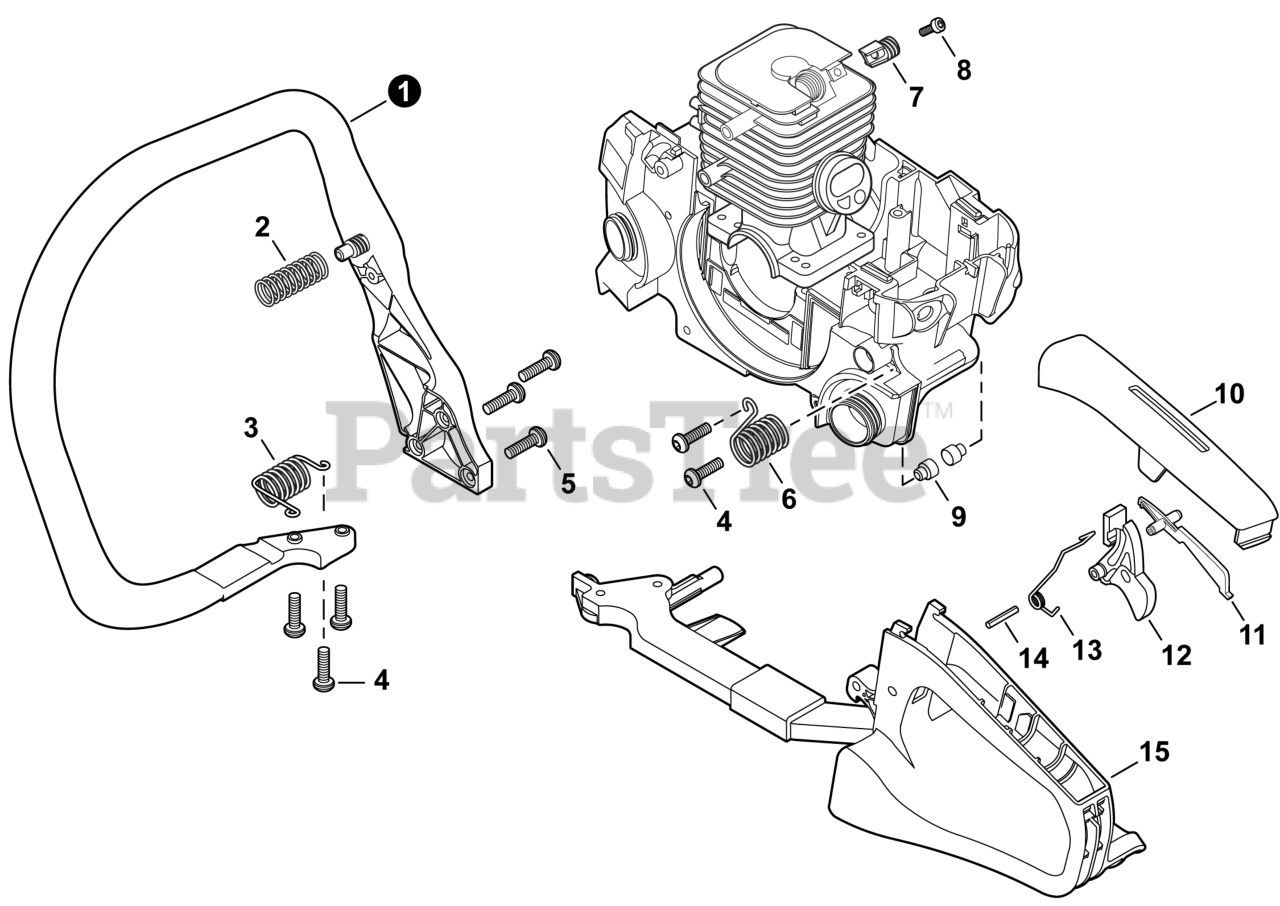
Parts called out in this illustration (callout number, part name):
1	HANDLE, FRONT
2	SPRING, COMPRESSION
3	SPRING, COMPRESSION
4	BOLT, TORX 5×16
5	BOLT, TORX 5×20
6	SPRING, COMPRESSION
7	HOLDER, SPRING
8	BOLT, TORX 5×12
9	CUSHION
10	COVER, HANDLE
11	LOCKOUT, THROTTLE
12	TRIGGER, THROTTLE
13	SPRING, TORSION
14	PIN, SPRING 4×25 SUS
15	HANDLE, REAR
